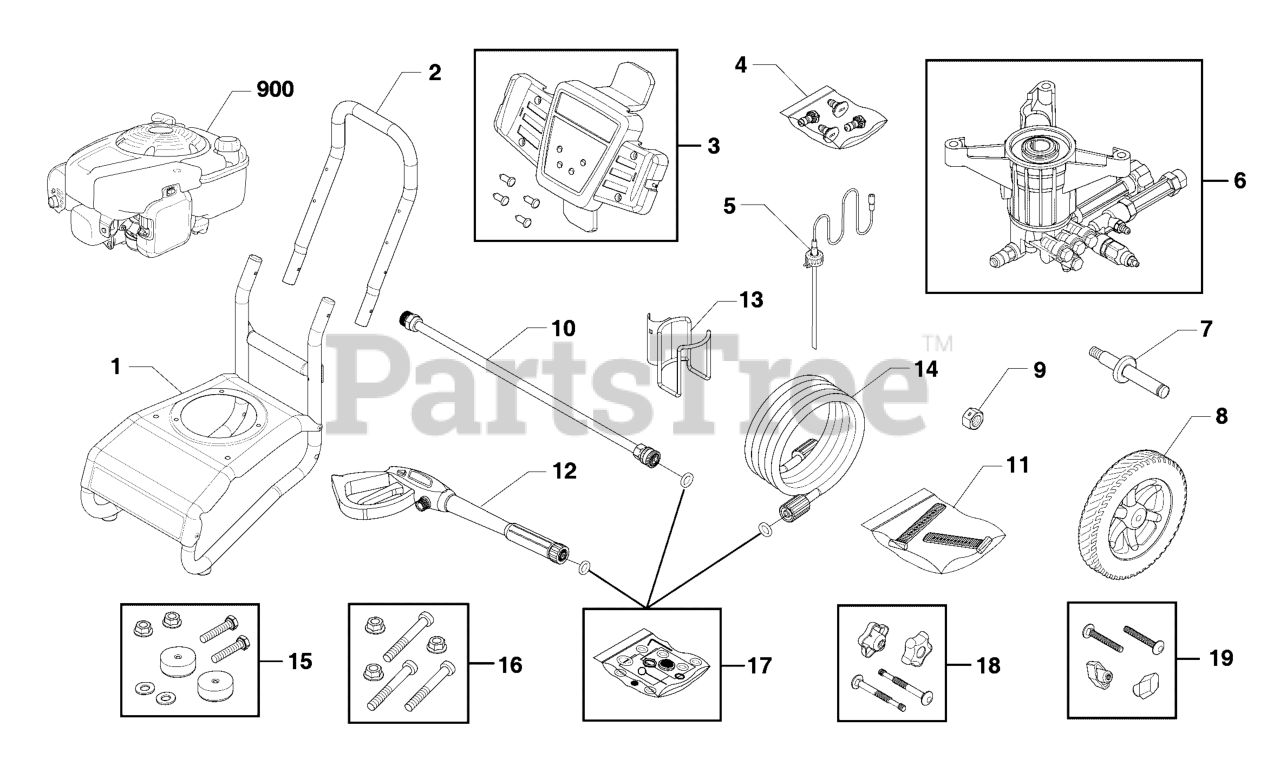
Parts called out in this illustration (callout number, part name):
4	KIT-QC NOZZLES
12	GUN
14	HOSE
15	MOUNT-VIBRATION
16	KIT, Hardware, Pump Mounting
17	KIT-O-RING MAINTENANCE
18	KIT, Hardware, Handle
900	ENGINE*
